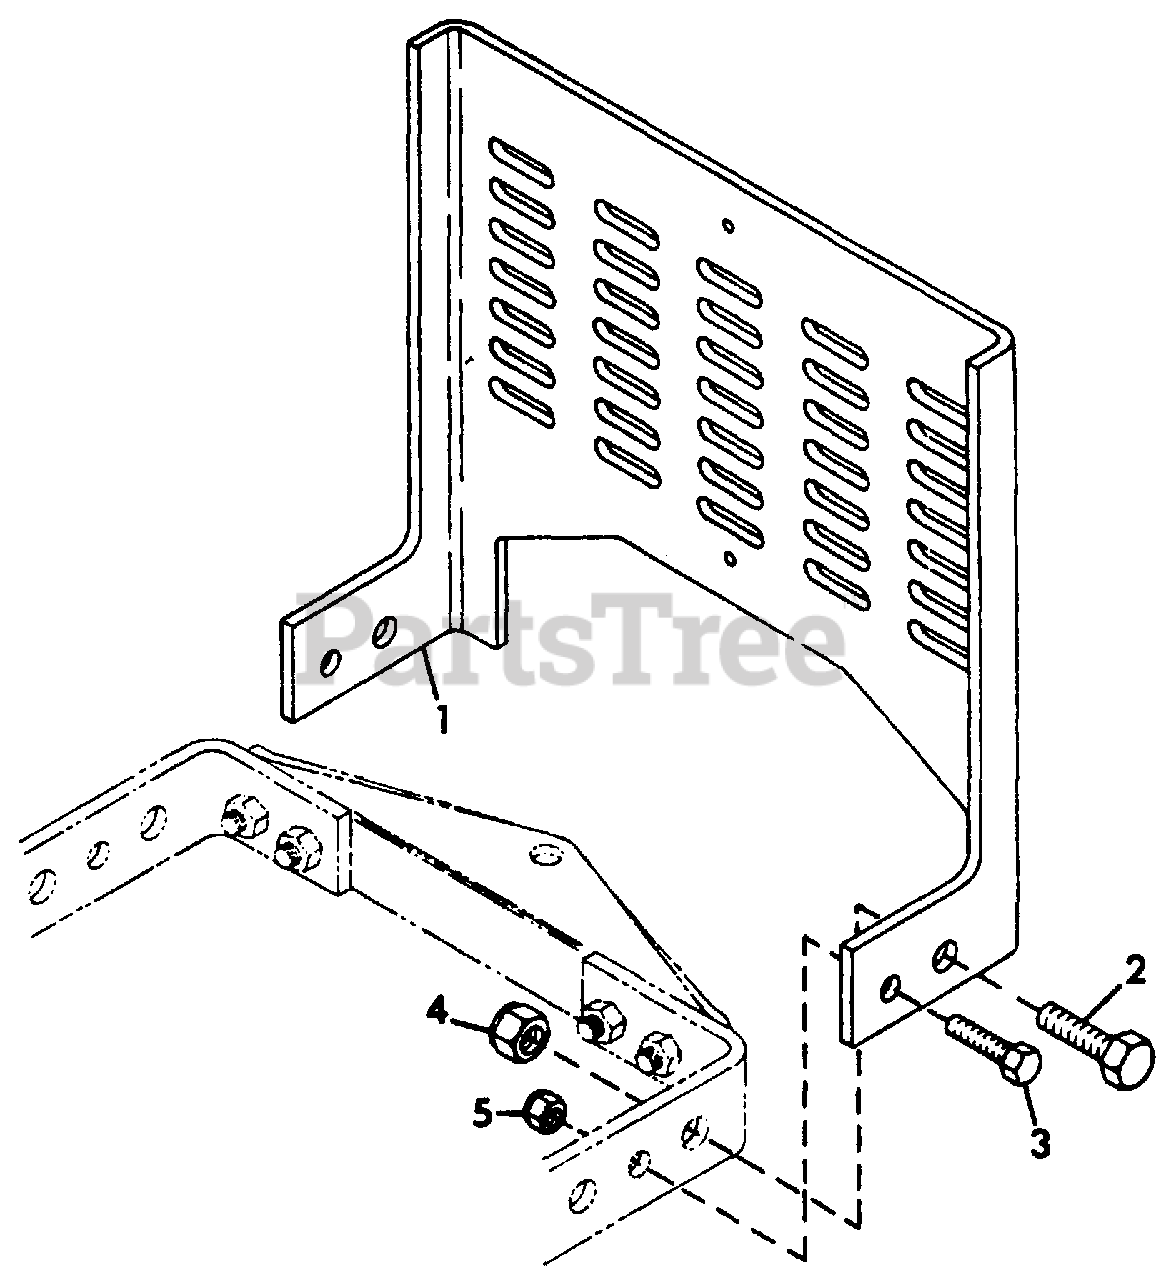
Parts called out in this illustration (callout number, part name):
1	GUARD, ENGINE
2	BOLT, HEX 5/8-11X2.00
3	BOLT, HEX 1/2-13X1.75
4	NUT, LOCK 5/8-11
5	NUT, LOCK 1/2-13
